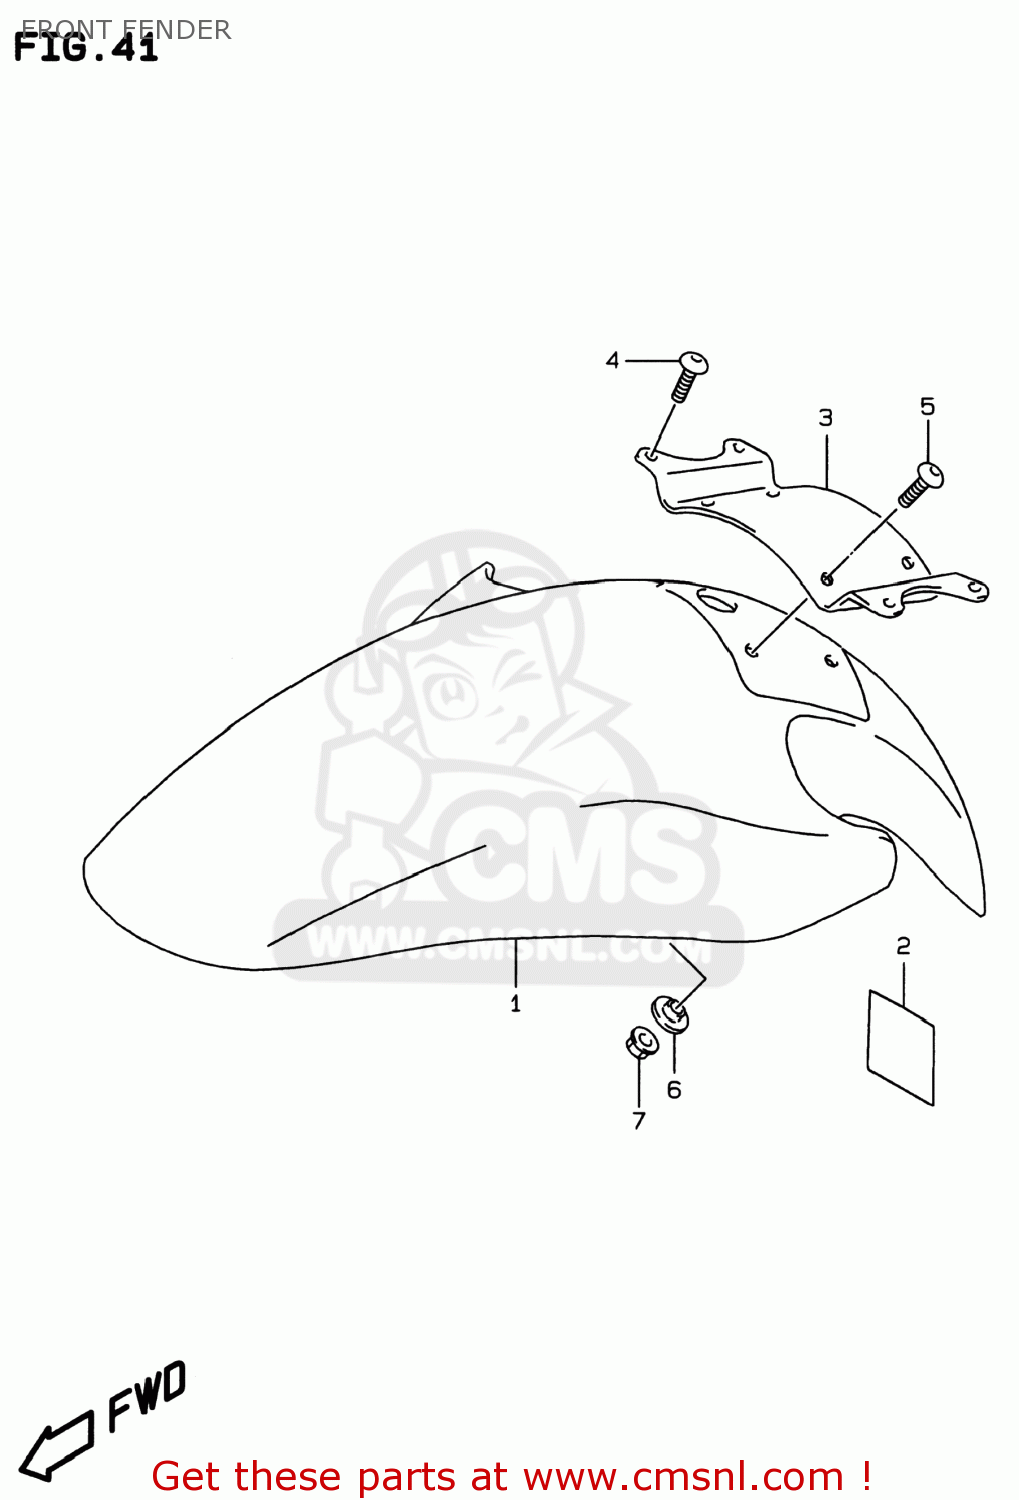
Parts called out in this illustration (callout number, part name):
1	FENDER SET,FR
2	CUSHION,BODY COWLING
3	BRACE,FR FENDER
4	SCREW(6X12)
5	SCREW(5X16)
6	WASHER
7	NUT
